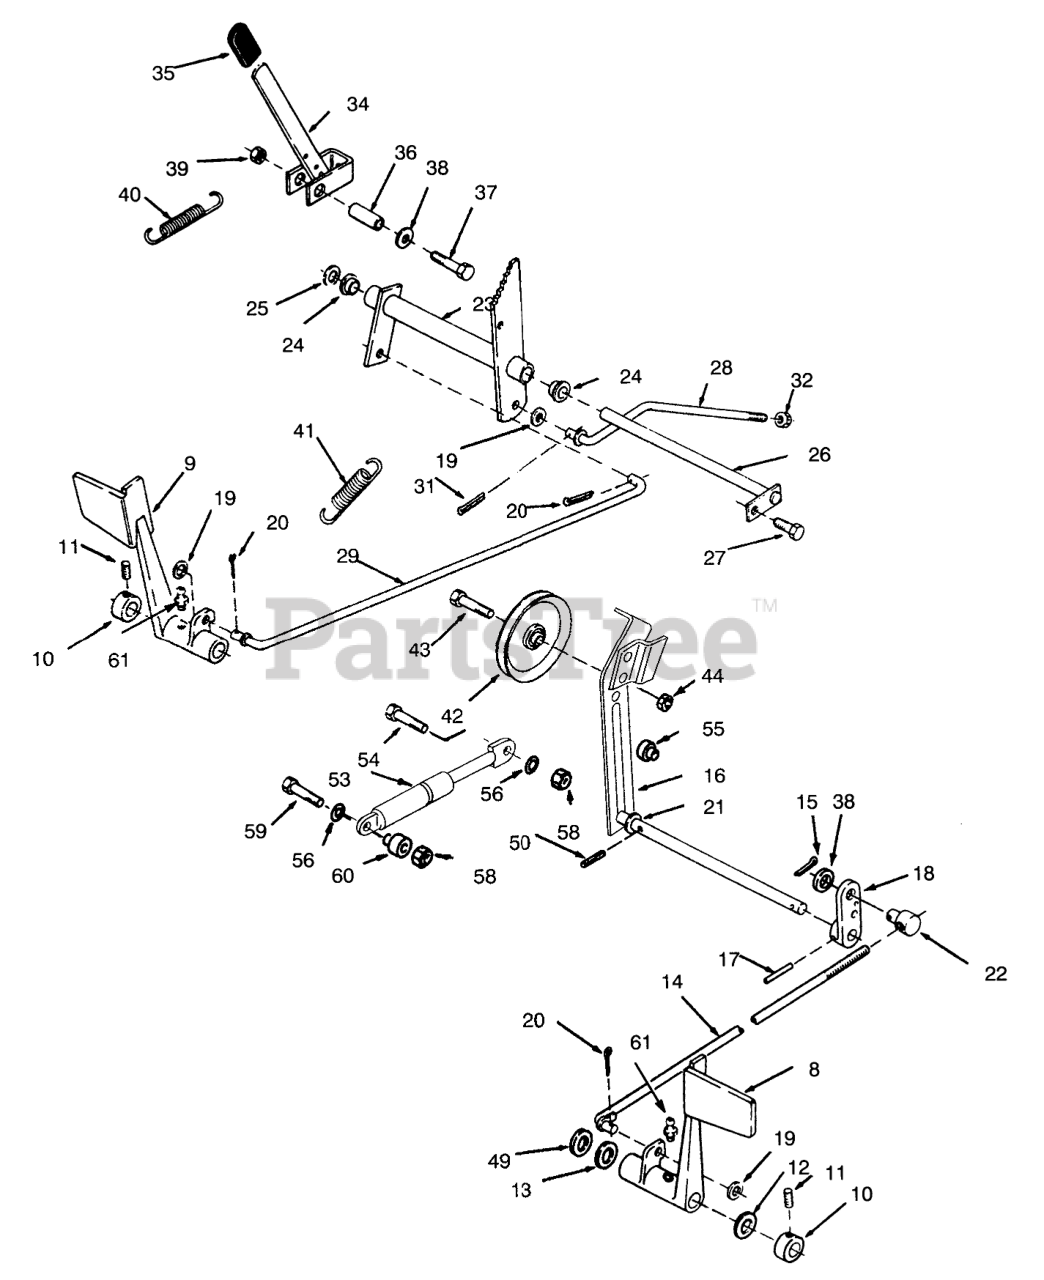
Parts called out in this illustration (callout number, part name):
8	PEDAL-CLUTCH R
9	Pedal-Brake
10	COLLAR
11	SCREW-HSH
12	WASHER-BOWED
13	WASHER
14	ROD AND GUIDE ASM
15	PIN-COTTER
16	Arm-Clutch Idler
17	PIN-SPIROL
18	Arm-Clutch Rod
19	WASHER-NYLON
20	PIN-COTTER
21	SHIM-WASHER
22	TRUNNION
23	Bellcrank Assy
24	BUSHING-FLANGED
25	WASHER-FLAT
26	ROD ASM
27	SCREW
28	ROD-REAR BRAKE
31	Hairpin Cotter
32	NUT-LOCK, NI
34	ASSY-BRAKE LEVER WAB
35	GRIP
36	SPACER
37	SCREW-HH
38	WASHER-FLAT
39	LOCKNUT-FLANGE
40	SPRING-BRAKE
41	SPRING-EXTENSION
42	PULLEY-IDLER
43	BOLT-SPECIAL HEX
44	NUT-HEX
49	Washer
50	PIN-SPIROL
53	ASS'Y-GAS SPRING
54	Capscrew
55	SPACER-SHOULDER-.200
56	WASHER-FLAT
58	NUT-LOCK, NI
59	SCREW-HH
60	SPACER-SHOULDER-.400
61	FITTING-GREASE
